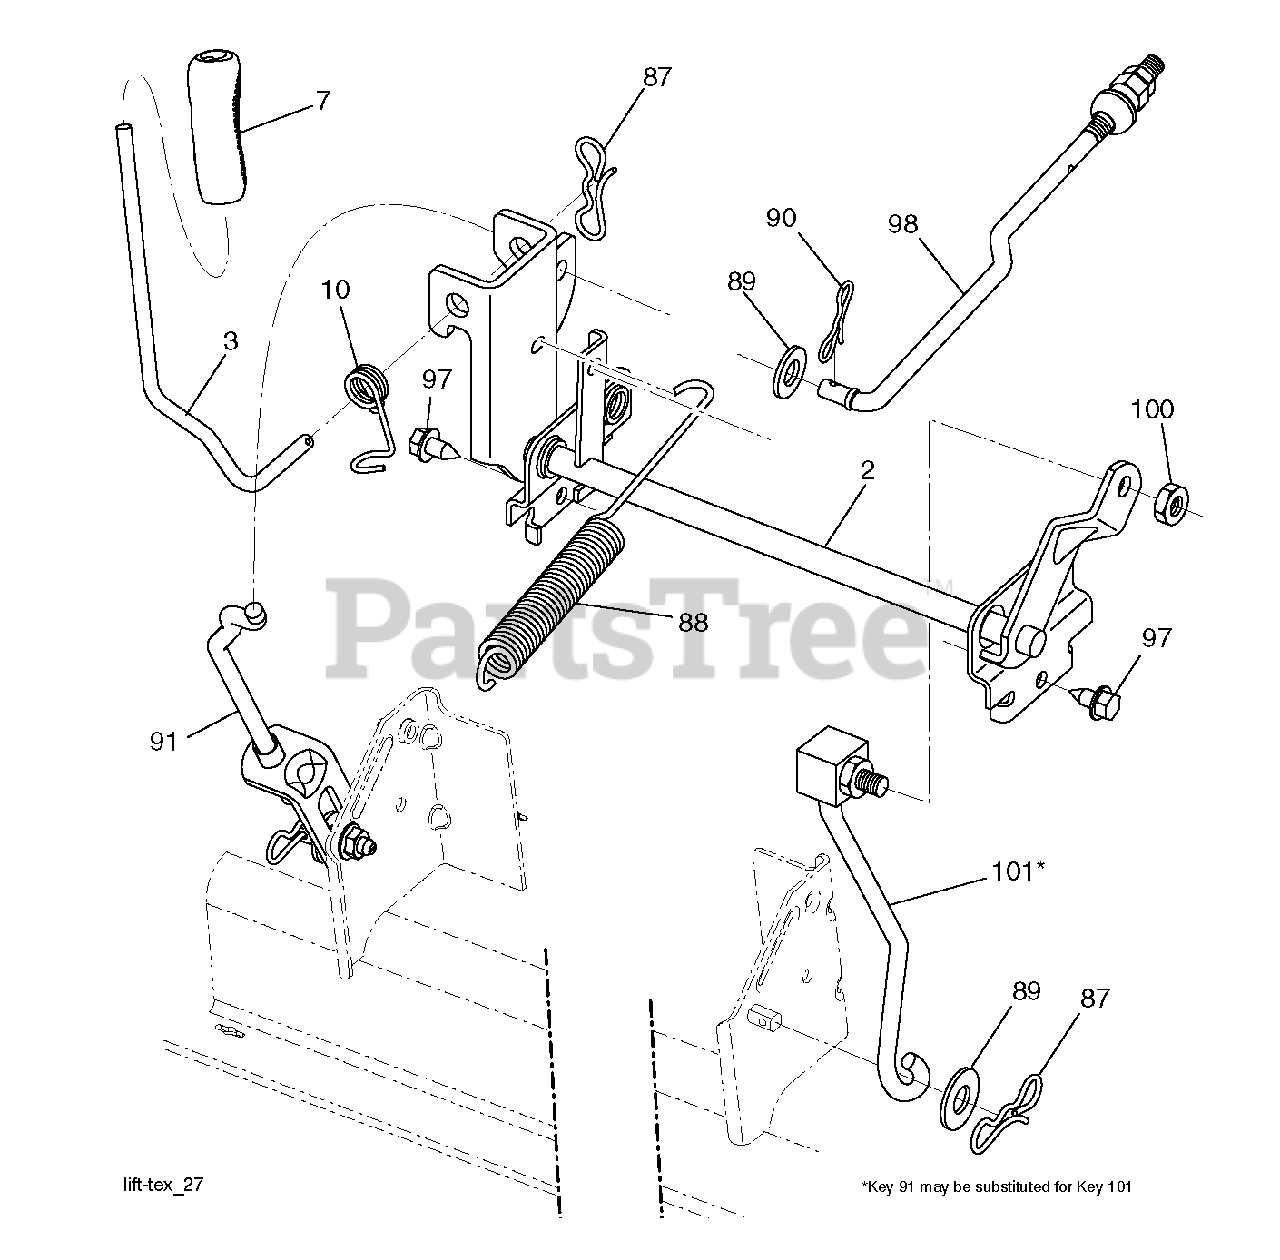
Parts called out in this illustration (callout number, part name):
2	SHAFT.ASM.CROSS.LIFT
3	LEVER.LIFT.HANDLE.LT
7	GRIP.HANDLE.LIFT.PVC.BLACK
10	SPRING.TORSION.LIFT.HANDLE
87	PIN.COTTER.7/16.BOW TI
88	SPRING.LIFT.ASSIST
89	WASHER.CLEAR.ZINC
90	PIN.COTTER.5/16.BOW TI
91	LINK.ASM.LIFT.REAR
97	SCREW, 3/8-16X3/4
98	LINK.ASM.SUSP.FRONT.MW
100	LOCKNUT
101	LINK.ASM.LIFT.FIXE.38/42/46"
